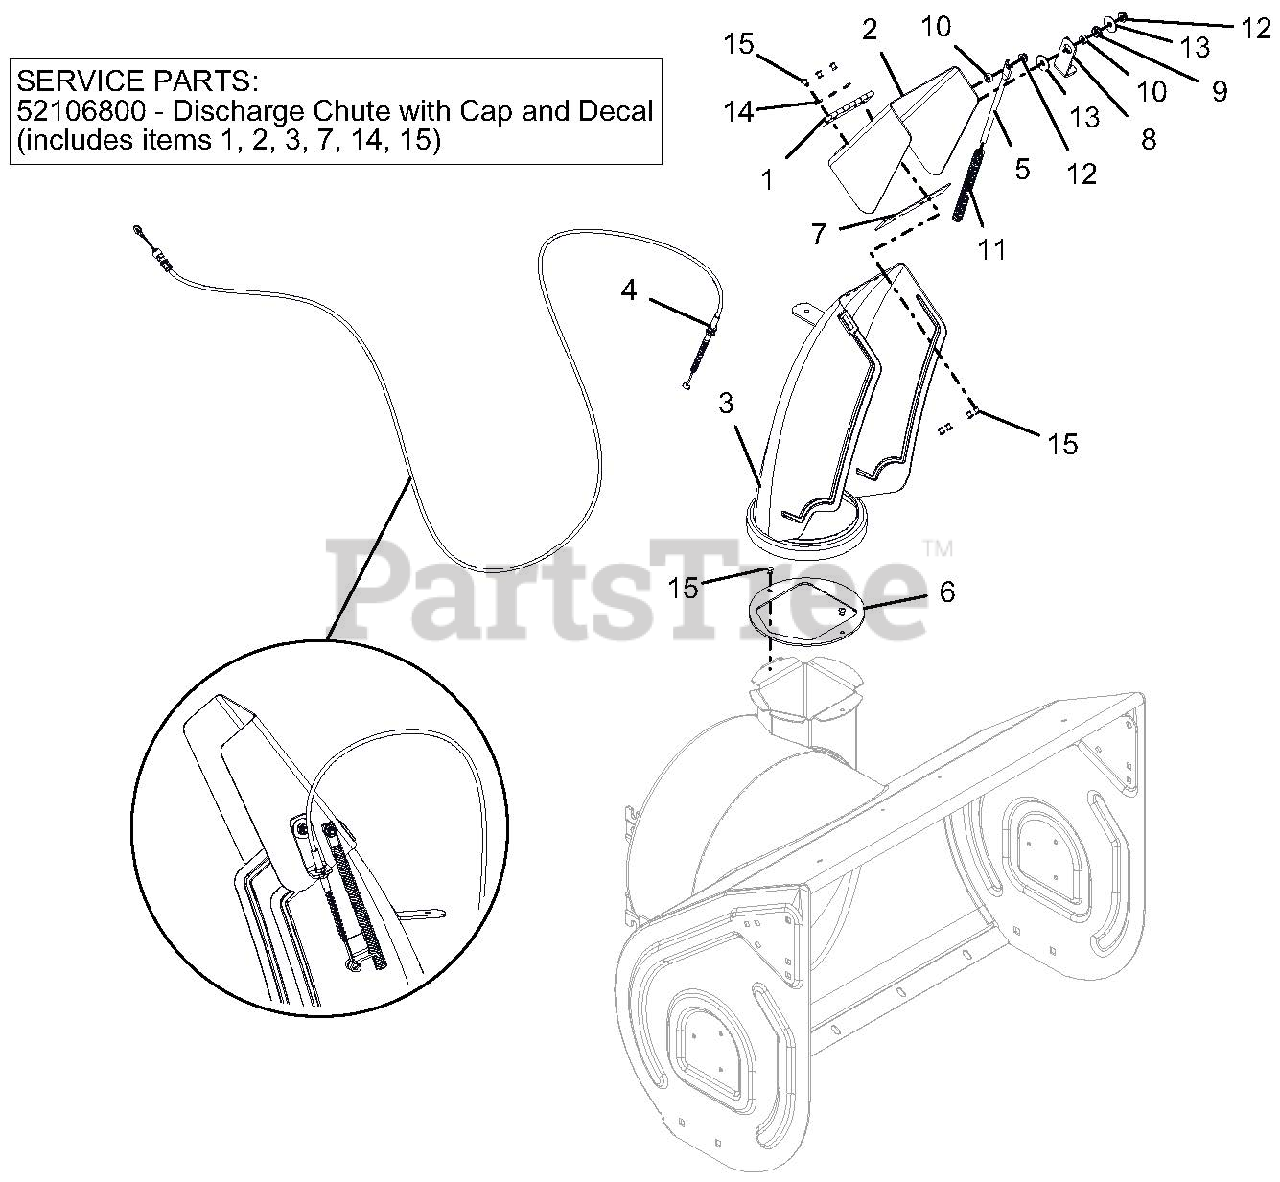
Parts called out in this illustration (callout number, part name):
2	CAP,LARGE,REMOTE
3	CHUTE,DISCHARGE,NOTCHED,QT
3	KIT, DISCHARGE CHUTE W/DEF QT2
4	CABLE, DEFLECTOR - DELUXE
5	ROD, DEFLECTOR CAP
6	BAFFLE, DISCHARGE NECK
7	CAP SEAL 5.50
8	BRACKET, CABLE ANCHOR
9	BUSHING, POLYLINER-.50 SNAPIN
10	BSHG-SLV .265X.500X.219
11	SG-COMP .08X.40X6.50 14#/IN
12	@NUT-LK-CTR-FLG .25-20 YWZC
13	WSHR-FL-STL .281X1.000X.063
14	WSHR-FL-STL .196X.500X.06 YZ
15	RVT-POP .187 YZ
